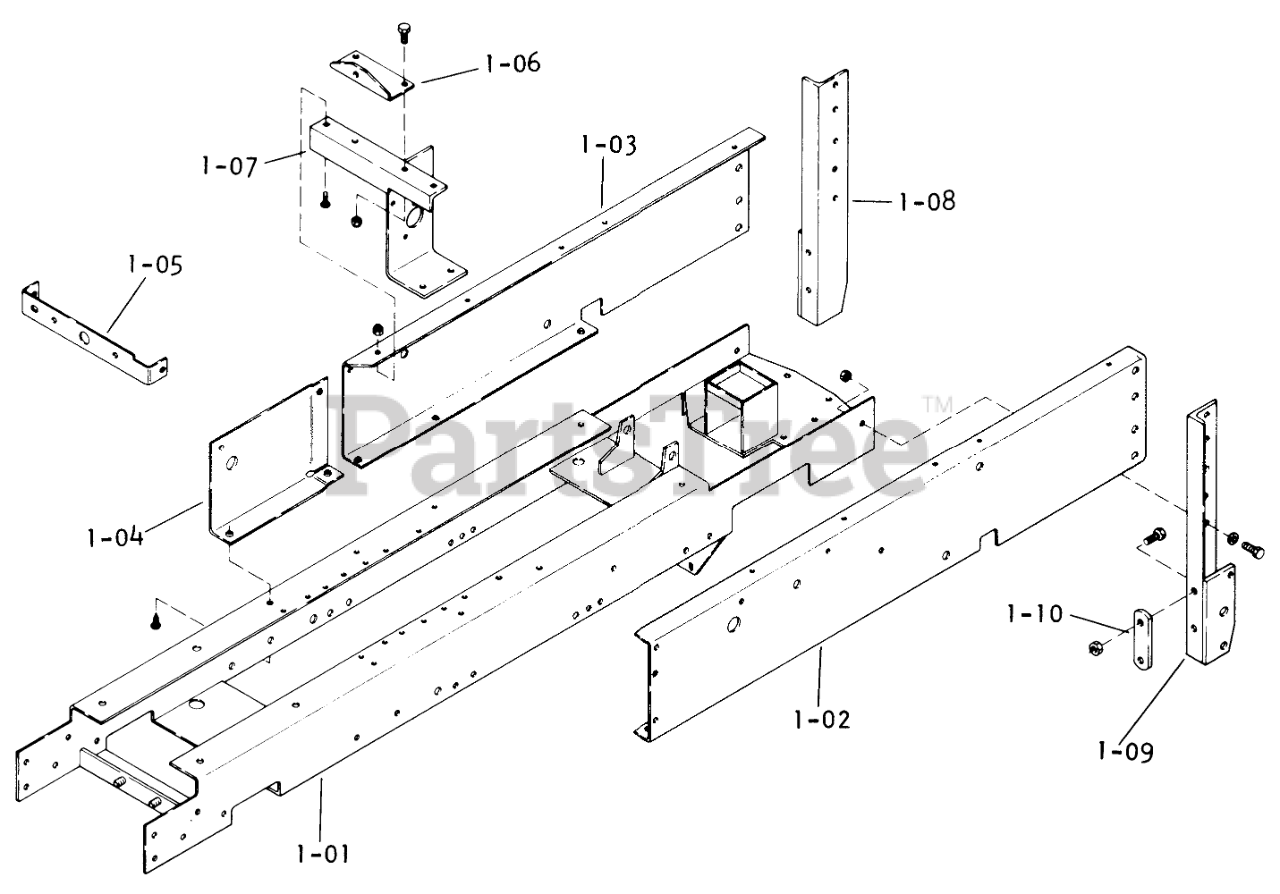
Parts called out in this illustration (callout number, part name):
1-01	Frame Assy.
1-02	Panel-Side, L.H.
1-03	Panel-Side, R.H.
1-04	Access Plate
1-05	Pump Mounting Plate
1-06	Pump Hanger Bracket
1-07	Steering Gear Support
1-08	Assy-Angle RH
1-09	Assy-Angle LH
1-10	BRACKET-REAR LINK MOUNTING
